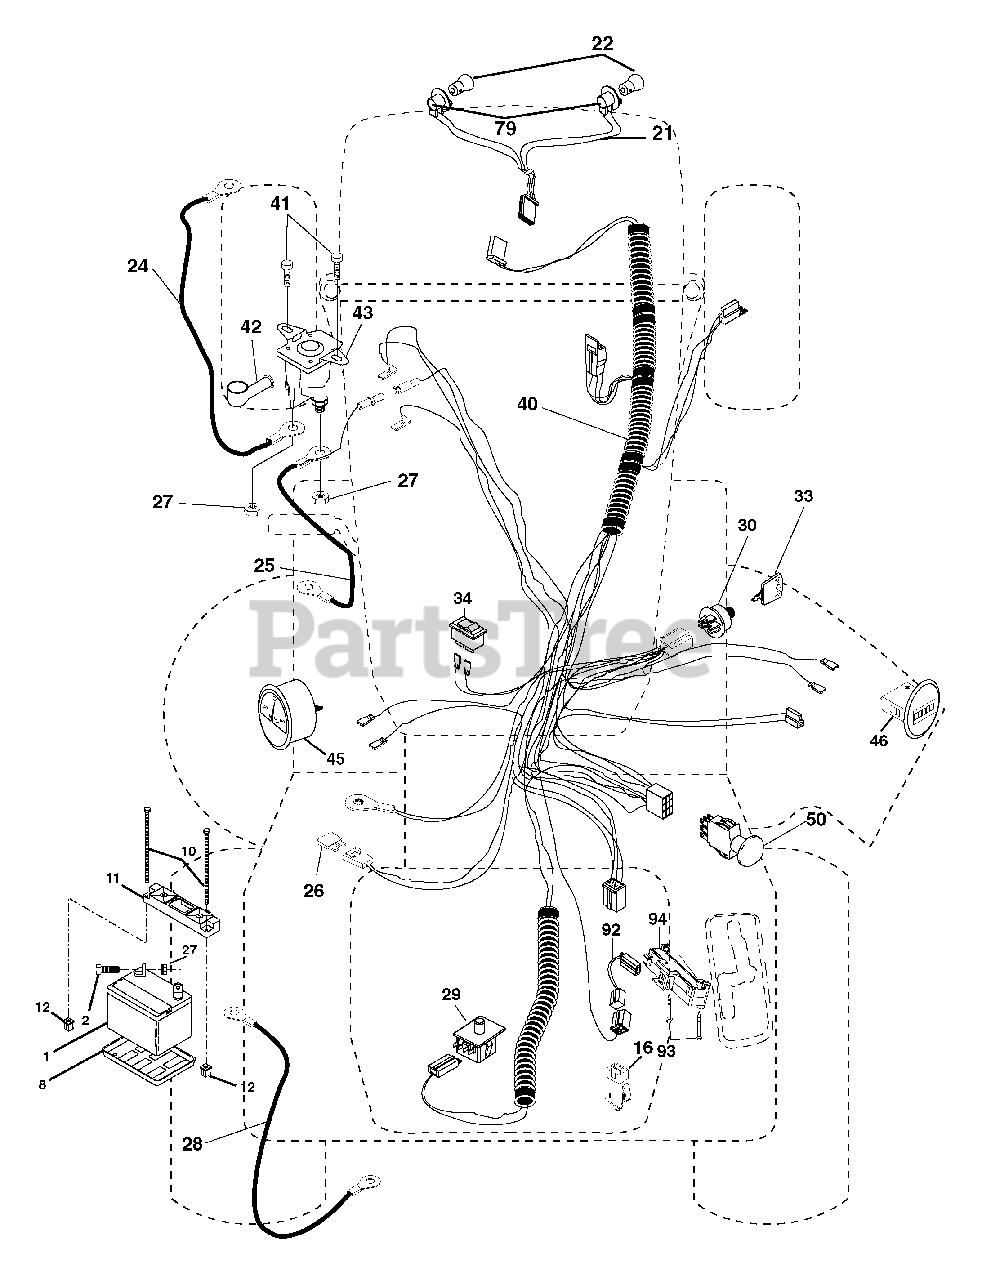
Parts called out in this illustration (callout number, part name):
1	Battery
2	Bolt Hex Head 1/4-20 x 3/4
8	Tray, Battery
10	Bolt, Battery Front 1/4-20 x 7.5 Zinc
11	Holddown Battery Front Mount
12	Nut, Push Nylon 1.4" Battery Front
16	Switch Interlock Push-In
21	Harness Socket Light w/4152J
22	Bulb Light
24	Cable Starter
27	Nut Keps Hex 1/4-20
28	Cable Bolt Ground
29	Switch, Seat
30	Switch, Ign
34	Switch Light/Reset B/B/Red
40	Harness Ign.
41	Screw Thd Cut 1/4-20 x 1/2
42	Cover, Terminal Red
43	Solinoid
50	Switch, PTO
79	Bulbholder Asm
92	Harness Pigtail Reverse Switch
93	Screw 10-14 x 2.0
94	Modual Reverse ROS
